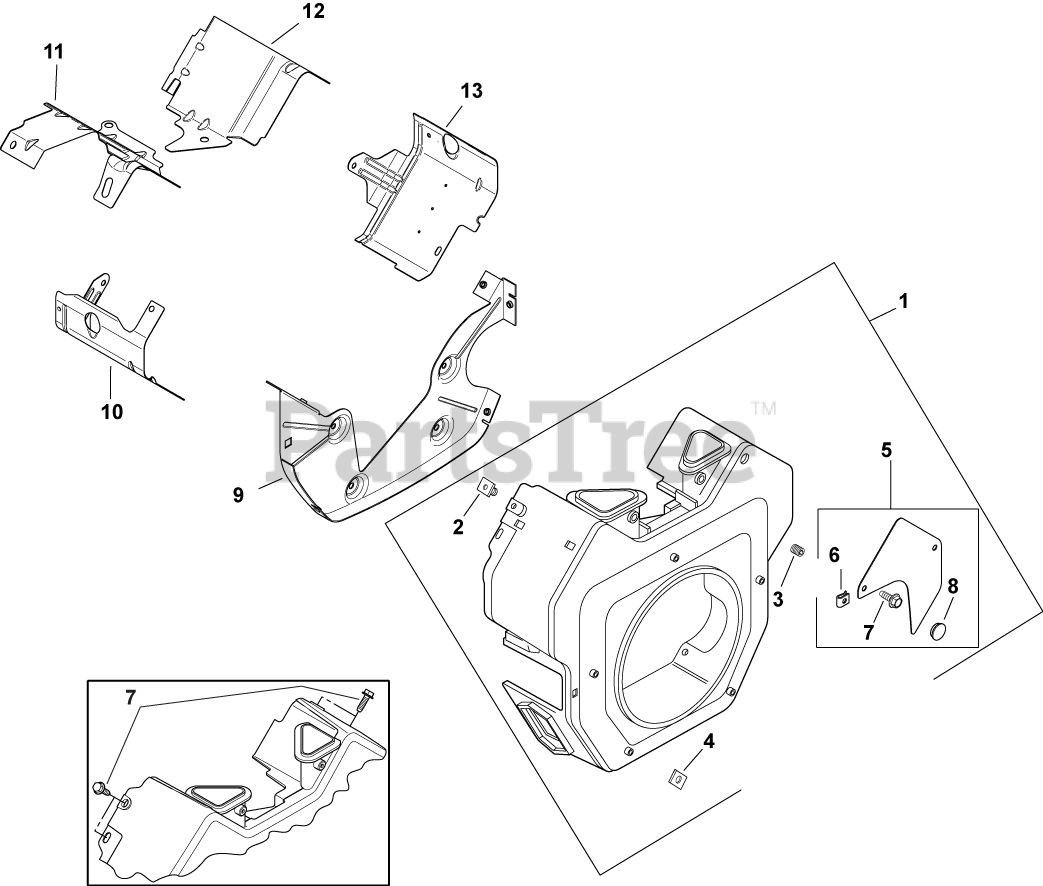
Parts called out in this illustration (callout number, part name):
1	BLOWER HOUSING ASSY-USE 84 027 11-S
2	NUT, PLASTIC
3	SCREW, SKT SET #10-24X1/4"
4	NUT, PLASTIC - BLACK
5	KIT, ACCESS PANEL USE 25 755 20-S
6	CLIP, MOUNTING-USE 25 154 13-S
7	SCREW,FLG THD FRM M6X1.0X16-(#25086397S)
8	PLUG, BUTTON 9/16
9	PLATE, BACKING-USE 24 146 59-S
11	BAFFLE,VALLEY #2SIDE(KM)-USE 24 063 70-S
12	BAFFLE, VALLEY (CH)-USE 24 063 93-S
13	BAFFLE, RIGHT BARREL-USE 24 063 85-S
